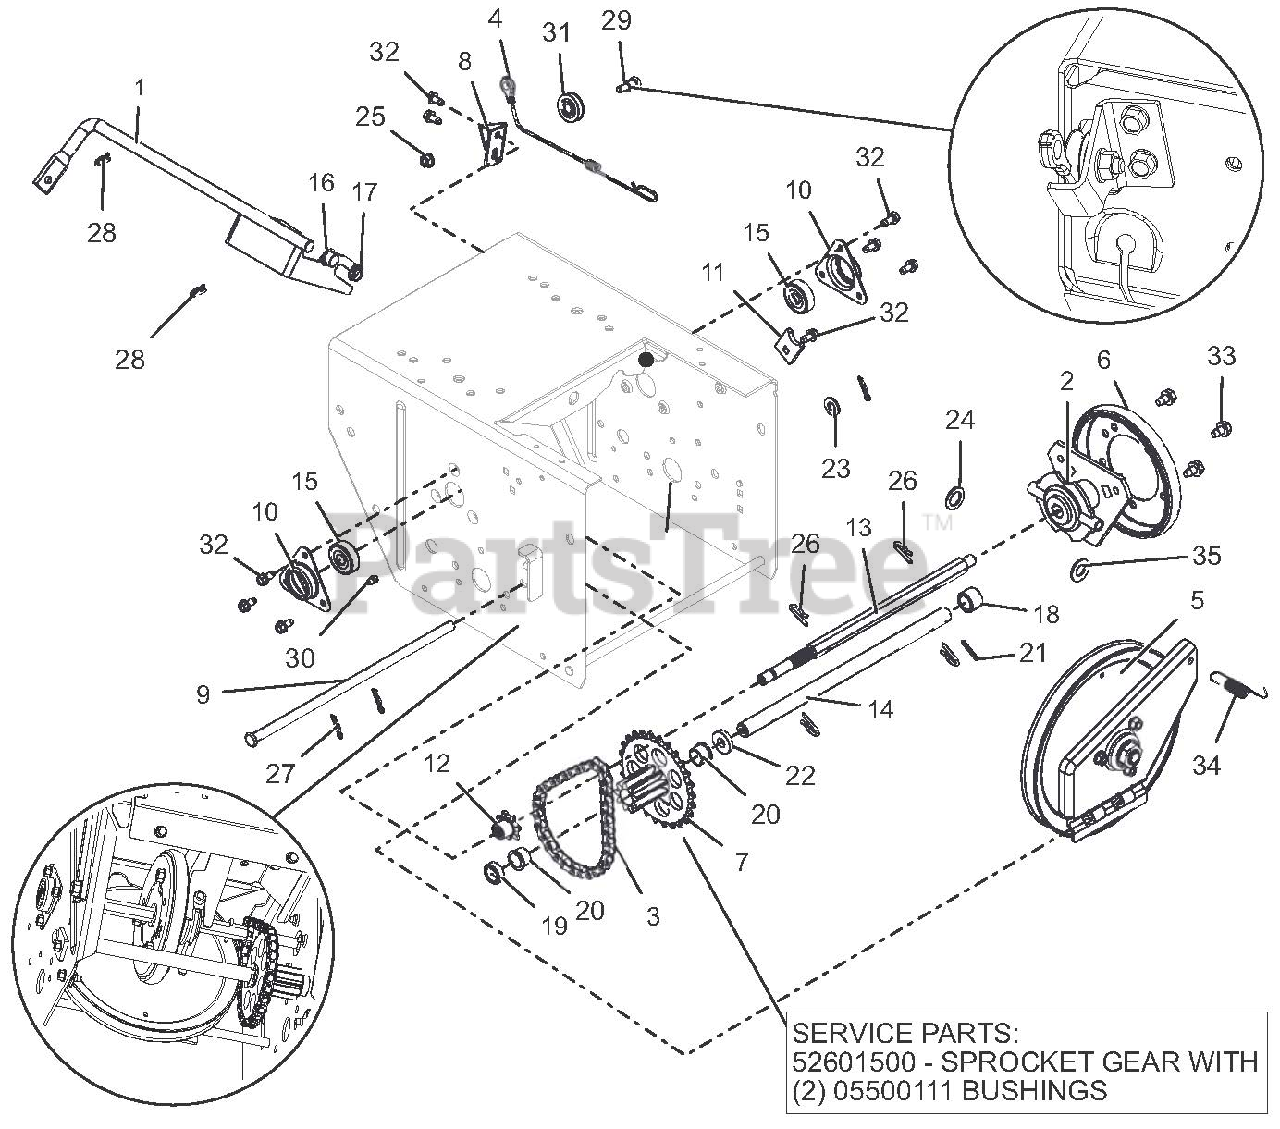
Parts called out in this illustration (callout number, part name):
1	ARM, SHIFT -WELDMENT
2	CARRIER, DRIVE DISK
3	CHAIN, ROLLER - #41 w/32 PITCHES
4	CABLE, LOWER TRACTION (SS & PRO)
5	PLATE, SWING-ASSY
6	DISC, FRICTION
7	PINION, SPROCKET
7	SPROKET GEAR
7	BUSHINGS
8	BRKT, CABLE PULLEY
9	PIN, PIVOT
10	FLANGE, BRG
11	TAB, ANTI - ROTATION
12	SPROCKET, PINION 7T W/SPLINE
13	SHAFT, HEX -W/SPLINE TRACK
14	SHAFT, PINION
15	BRG-BALL .437X1.375X.437
16	BUSHING, POLYLINER - .50 SPLIT
17	BSHG, POLYLINER - .50 SNAP-IN
18	SPCR, .635 X .880 X .611
19	BSHG, SLV , .635X.880X.305
20	BSHG, FLG .625 X .750 X .500 X .875
21	PIN-ROLL .125X1.00
22	WSHR-FL-STL .406X1.00X.188 YWZC
23	WSHR-FL-STL.406X.812X.065 YWZ
24	WSHR-FL-STL .630X1.005X.062 YWZC
25	NUT, LK-TOP-FLG .25-20 YWZC
26	PIN, SPRING CLIP
27	PIN-HAIR, ENDRIES #25 YWZC
28	CLIP, SPRING
29	BOLT, SHLDR -.375 X .375 X .25-20
30	ZERK, FITTING .25X.125 DRIVE IN
31	PULLEY, CABLE
32	SCR-TAP .25-20X.50 HWH TR YWZ
33	SCR-TAP .31-18X.50 HWH TR YWZ
34	SPRG, EXTENSION
35	WSHR-FL-STL .505X1.00X.062 YWZC
